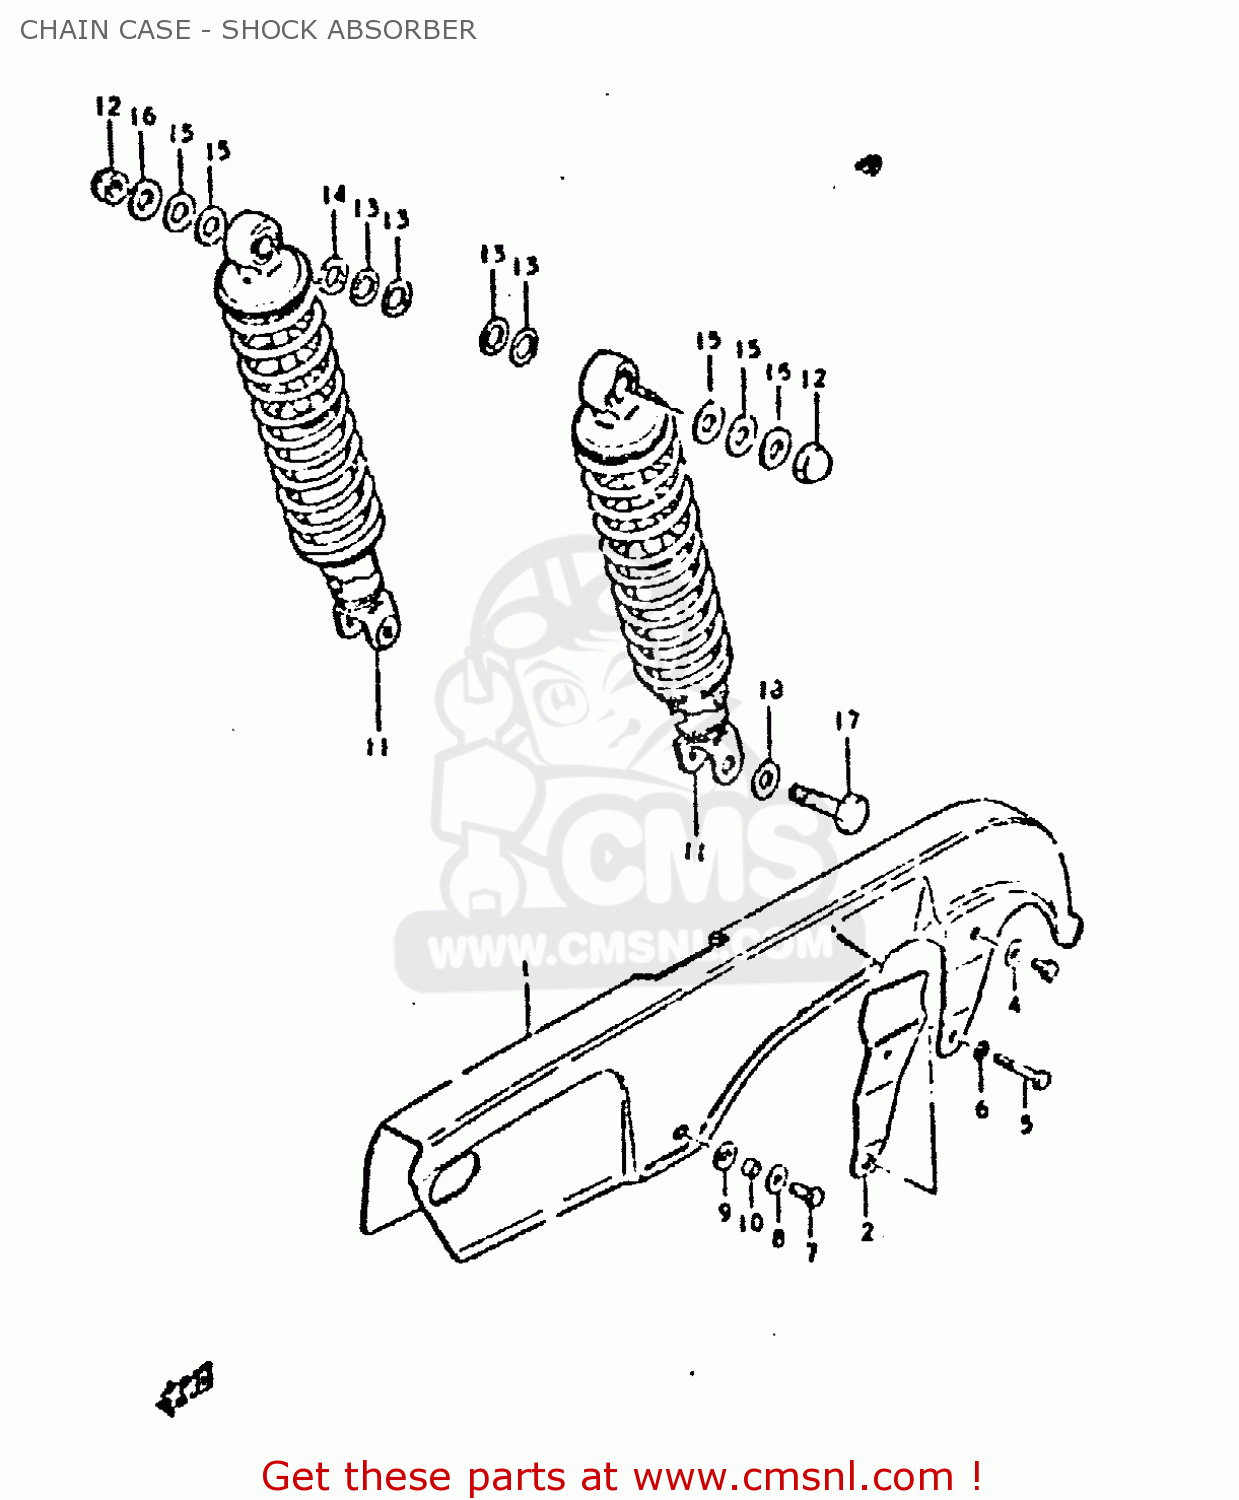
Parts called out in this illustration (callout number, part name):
1	CASE,CHAIN
2	REINFORCEMENT,CHAIN CASE
3	BOLT(6X8)
4	WASHER
5	BOLT
6	LOCK WASHER
7	BOLT
8	WASHER(6.5X18X1)
9	CUSHION
10	SPACER (6.1X8X5.2)
11	SHOCK ABSORBER, REAR
12	NUT, LOWER LH
13	WASHER
14	WASHER (12.5X24X3.2)
15	WASHER
16	WASHER(10.5X24X3.2)
17	BOLT(10X36)
18	WASHER
